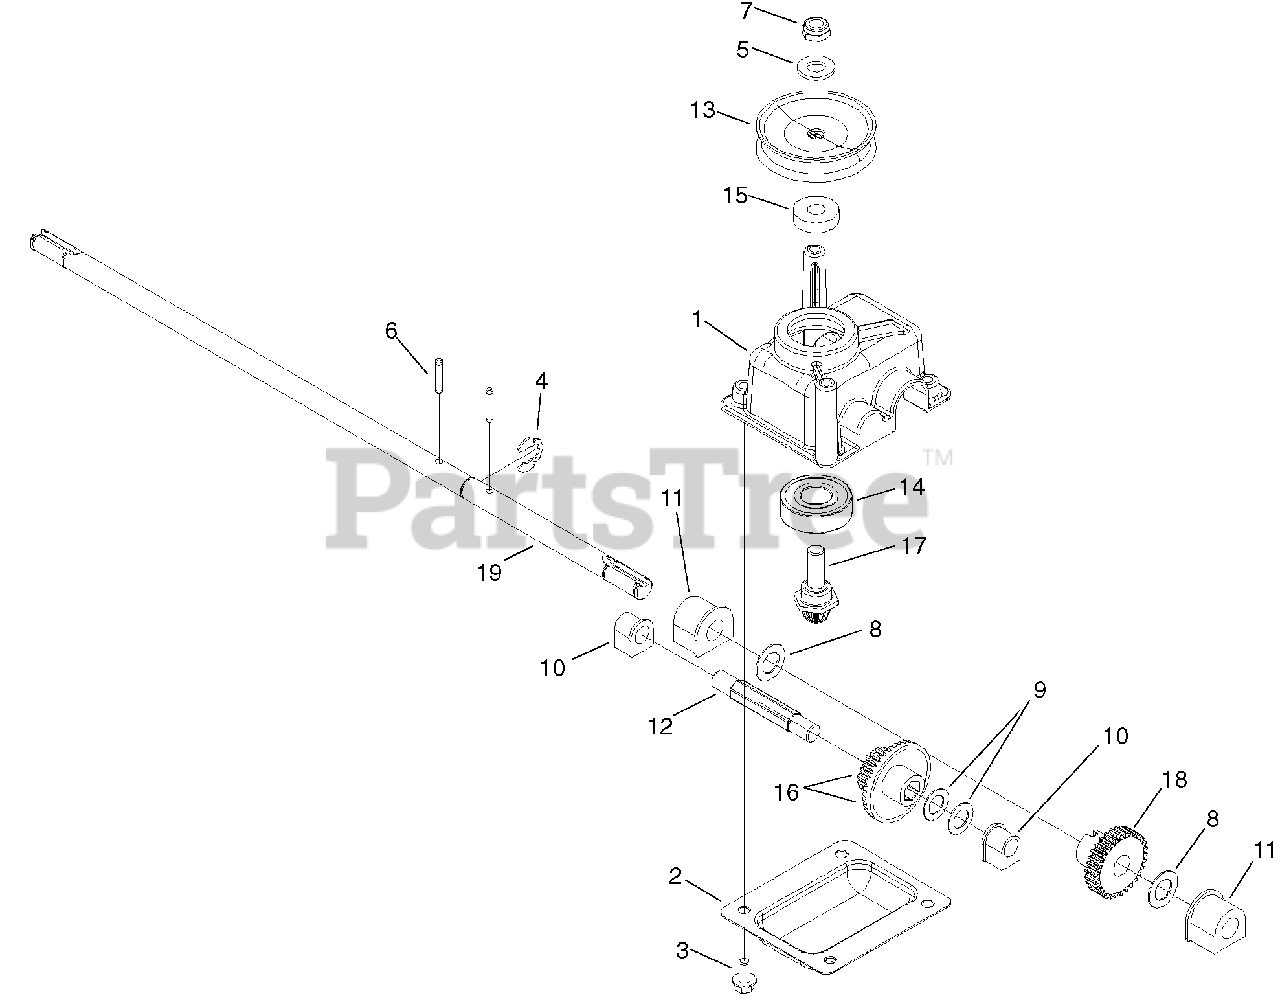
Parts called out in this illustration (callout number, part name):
1	CASE-GEAR
2	COVER-CASE, GEAR
3	SCREW-HWH
4	RING-RETAINING
5	WASHER-FLAT
6	PIN-GROOVE
7	NUT-LOCK, NI
9	WASHER-THRUST
11	BUSHING-OUTPUT
12	SHAFT-INTERMEDIATE
13	PULLEY-HALF
14	BEARING-BALL
16	GEAR-19T SPUR, 37T BEVEL
17	GEAR-PINION, BEVEL
19	SHAFT-OUTPUT
